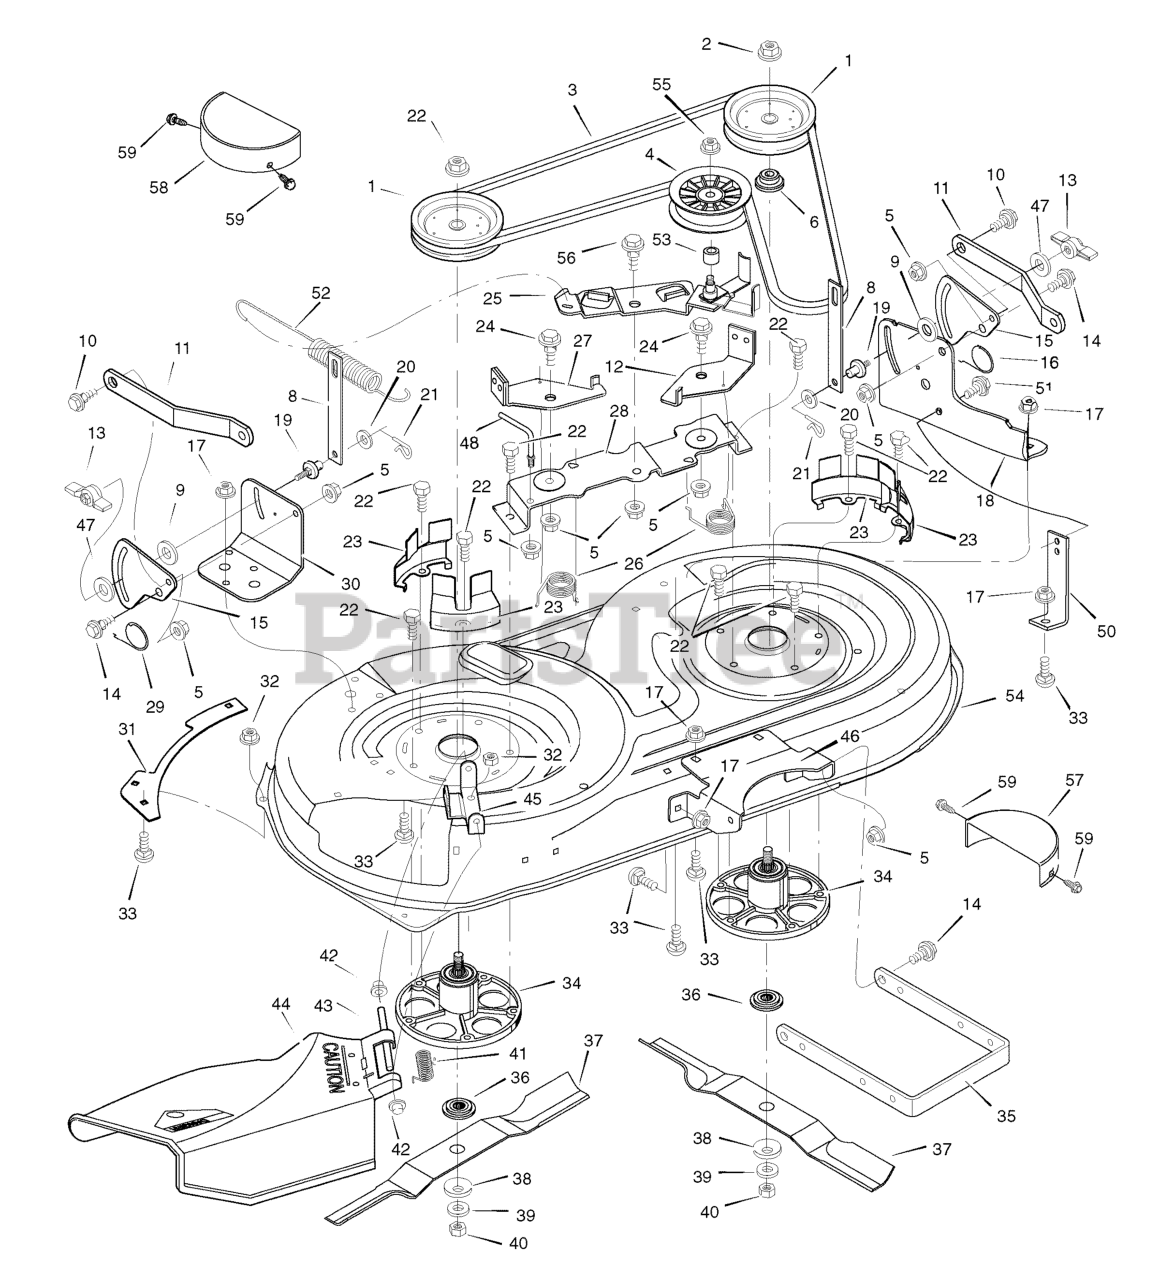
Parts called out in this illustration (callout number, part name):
1	Pulley, Jackshaft
2	Nut, Hex
3	Belt, Mower Drive
4	Pulley, Idler
5	Nut, Flange
6	Spacer, Pulley
8	Link, Lift
9	Pad, Friction
10	Bolt, Shoulder
11	Bracket, Suspension
12	Pad Assembly, Left Brake
13	Knob
14	Bolt, Shoulder
15	Plate, Suspension
17	Nut, Flange
18	Bracket, Left Suspension
19	Pin, Hanger
21	Pin, Cotter
23	Cover, Pulley
24	Bolt, Shoulder
25	Arm, Idler
27	Pad Assembly, Right Brake
28	Bracket Assembly, Brake
30	Bracket, Right Suspension
32	Nut, Flange
33	Bolt, Carriage
34	Mandrell
35	Bracket, Suspension
36	Adapter, Blade
42	Cap, Push On
43	ROD, Deflector
44	Deflector Assembly
45	Bracket, Deflector
46	Bracket, Front Hanger
48	Guide, Belt
50	Bracket, Support
52	Spring, Extension
54	Housing - Export Blade
55	Nut, Flange
56	Bolt, Shoulder
57	COVER, Pulley L.H.
58	GUARD, Belt R.H.
